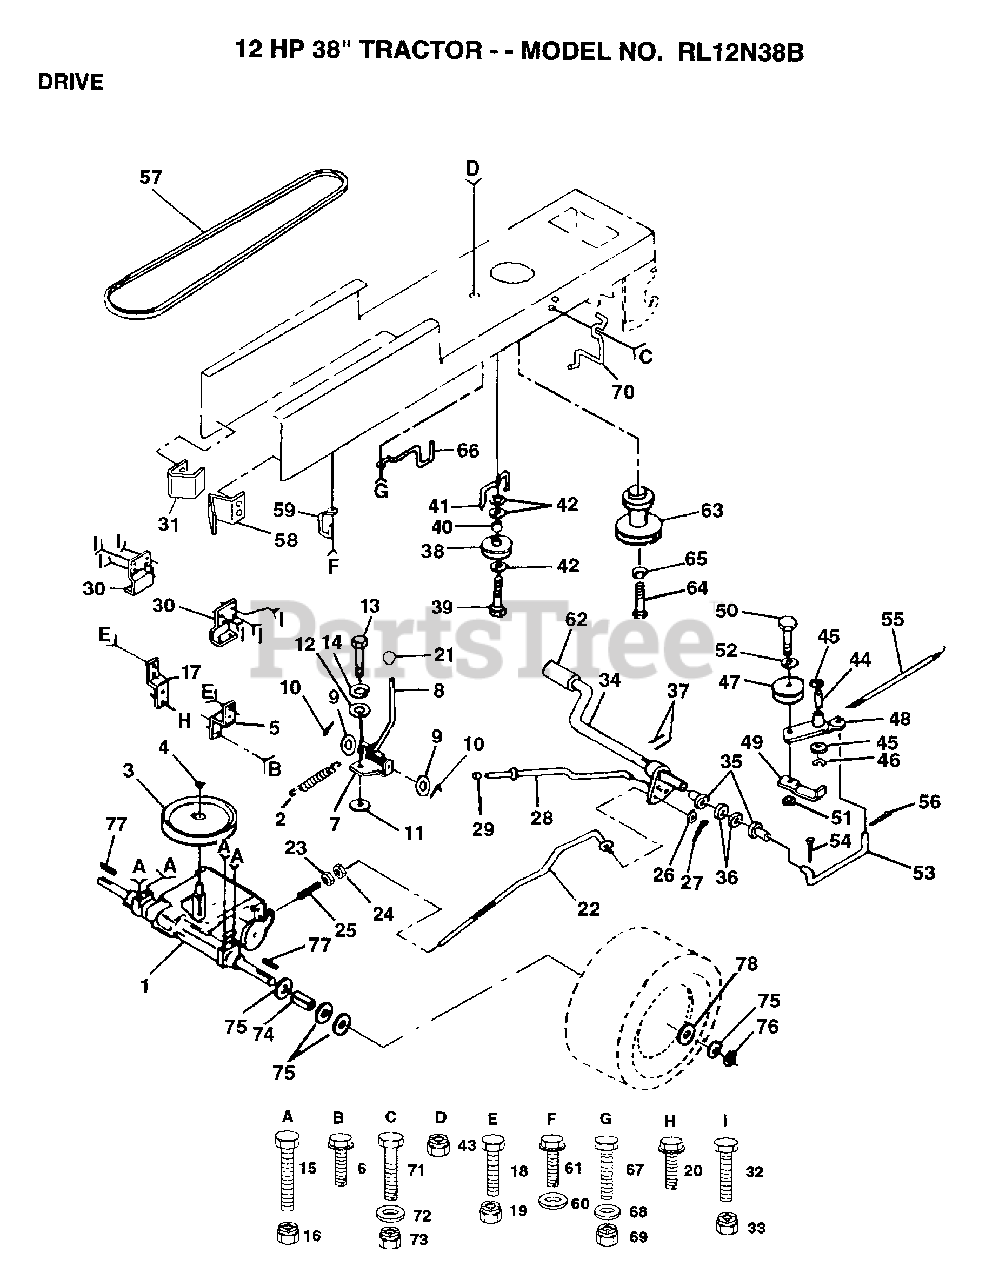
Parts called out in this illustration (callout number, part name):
3	PULLEY TRANS
5	STRAP TORQUE
6	SCREW
7	PLATE SHIFT LT
8	ROD SHIFTER
9	WASHER
10	PIN COTTER 1/8
11	WASH-SHFT PLT LT
12	WASHER LT
14	LOCKWASHER
15	BOLT
17	STRAP TORQUE
20	SCREW
21	CONTROL KNOB LT
23	NUT
24	NUT
25	SPRING ROD LT
26	WASHER
27	COTTER PIN
28	PARKING BRAKE ROD
30	BRACKET LT
31	"KEEPER,BELT LH T"
32	BOLT
35	NYLON BEARING
36	WASHER LT
38	PULLEY.IDLER.FLAT
39	BOLT
40	SPACER T
41	BELT KEEPER LT
42	WASHER
44	"LY, BEARING"
45	WASHER LT
46	KLIP RING
48	ARM IDLER
49	RETAIN BELT
52	WASHER
53	"LINK, CLUTCH T"
54	COTTER PIN
55	"SPRING, RETURN LT"
56	COTTER PIN
57	BELT-V.90.0.GD.DR
58	"KEEPER,BELT RH T"
60	WASHER
61	SCREW
62	PEDAL COVER T
64	BOLT HEX 7/16-20X4 GR 5
65	LOCKWASHER
66	KEEPER.BELT.ENG.L
67	BOLT
68	WASHER
70	KEEPER BELT ENG
71	BOLT
72	WASHER
74	SPACER LT
75	WASHER
76	E-RING LT
77	SQUARE KEY
78	WASHER
